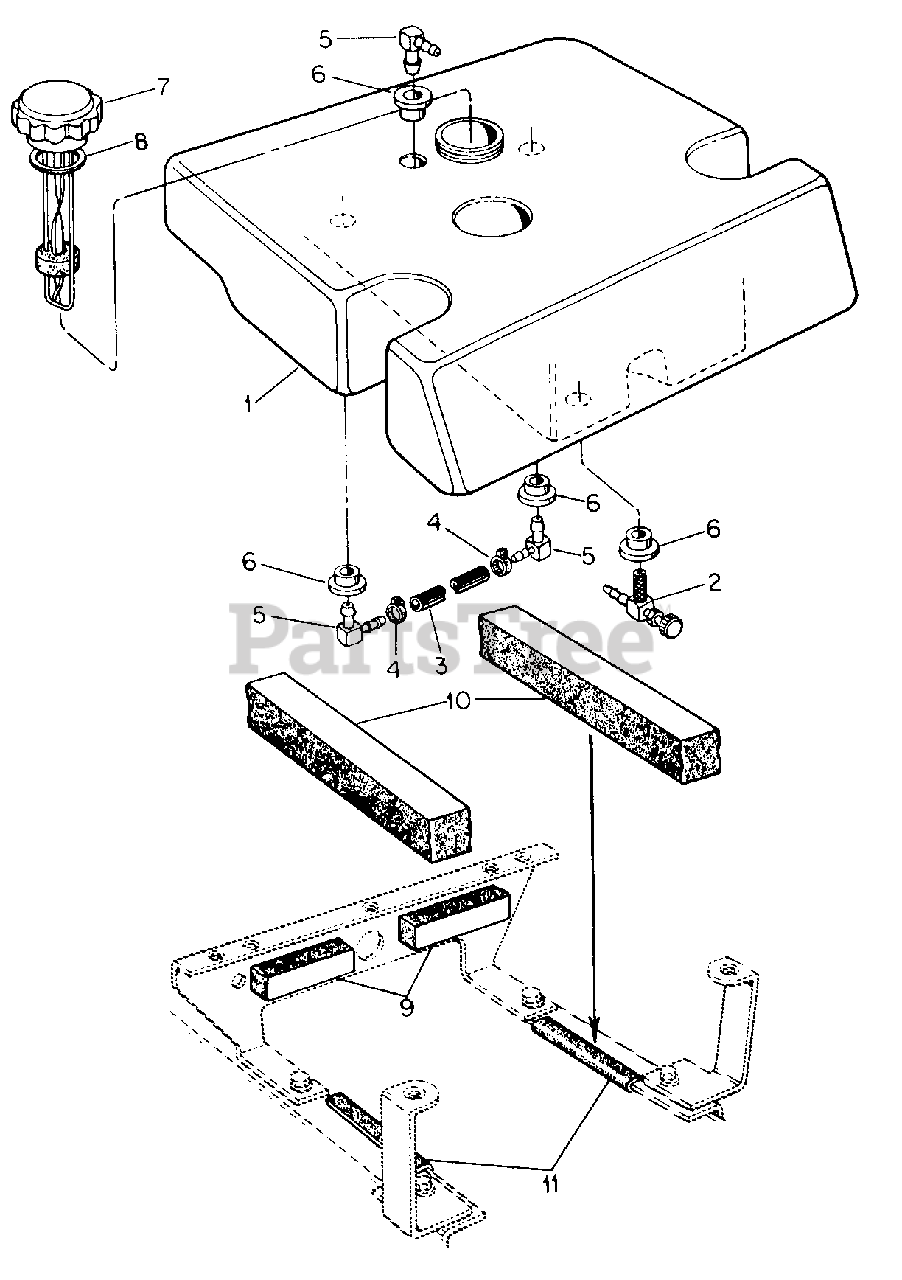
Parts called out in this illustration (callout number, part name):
1	Tank Assy, Fuel
2	Valve, Shut-Off
3	Line, Fuel
4	Clamp
5	Fitting, Fuel Tank
6	Bushings
7	Cap, Fuel Tank
8	Gasket, Fuel Tank Cap
9	Strip, Foam Gasket Sealing, 3 Inches Lg
10	Strip, Foam Gasket Sealing, 5 Inches Lg
11	Strip, Trim, 4 Inches Lg
